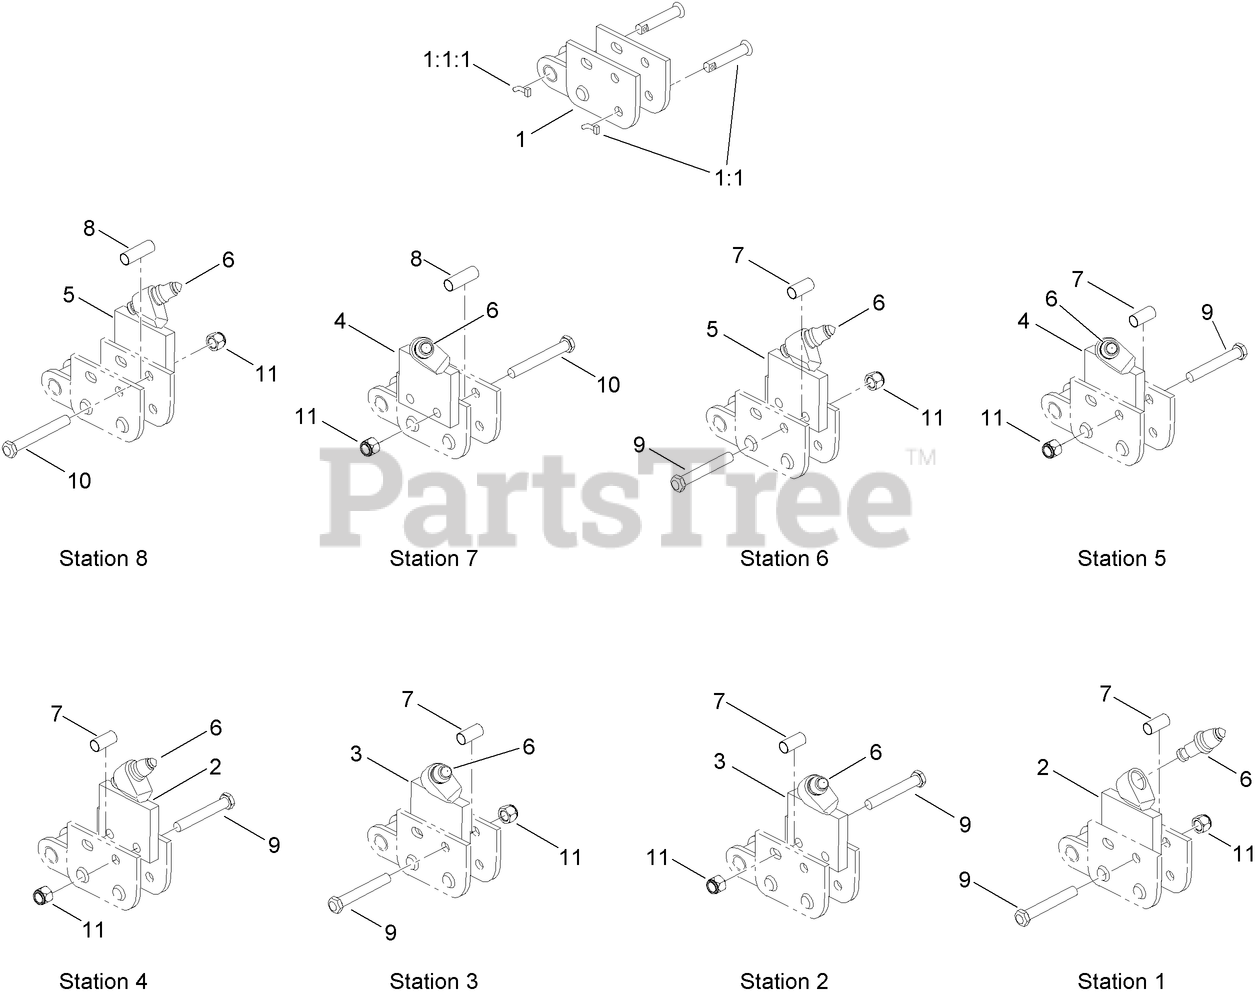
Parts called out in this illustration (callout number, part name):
1	CHAIN REPAIR LINK ASM
1:1	NOTCHED PIN AND KEEPER ASM
1:1:1	PIN-KEEPER
2	HOLDER-BIT, RH CENTER
3	HOLDER-BIT, LH CENTER
4	HOLDER-BIT, RH
5	HOLDER-BIT, LH
6	BIT-CARBIDE, FULL CAB
7	SPACER-TUBE, INSIDE ADAPTER
8	SPACER-TUBE, OUTSIDE MOUNT
9	BOLT-HH
10	BOLT-HH
11	NUT-LOCK
